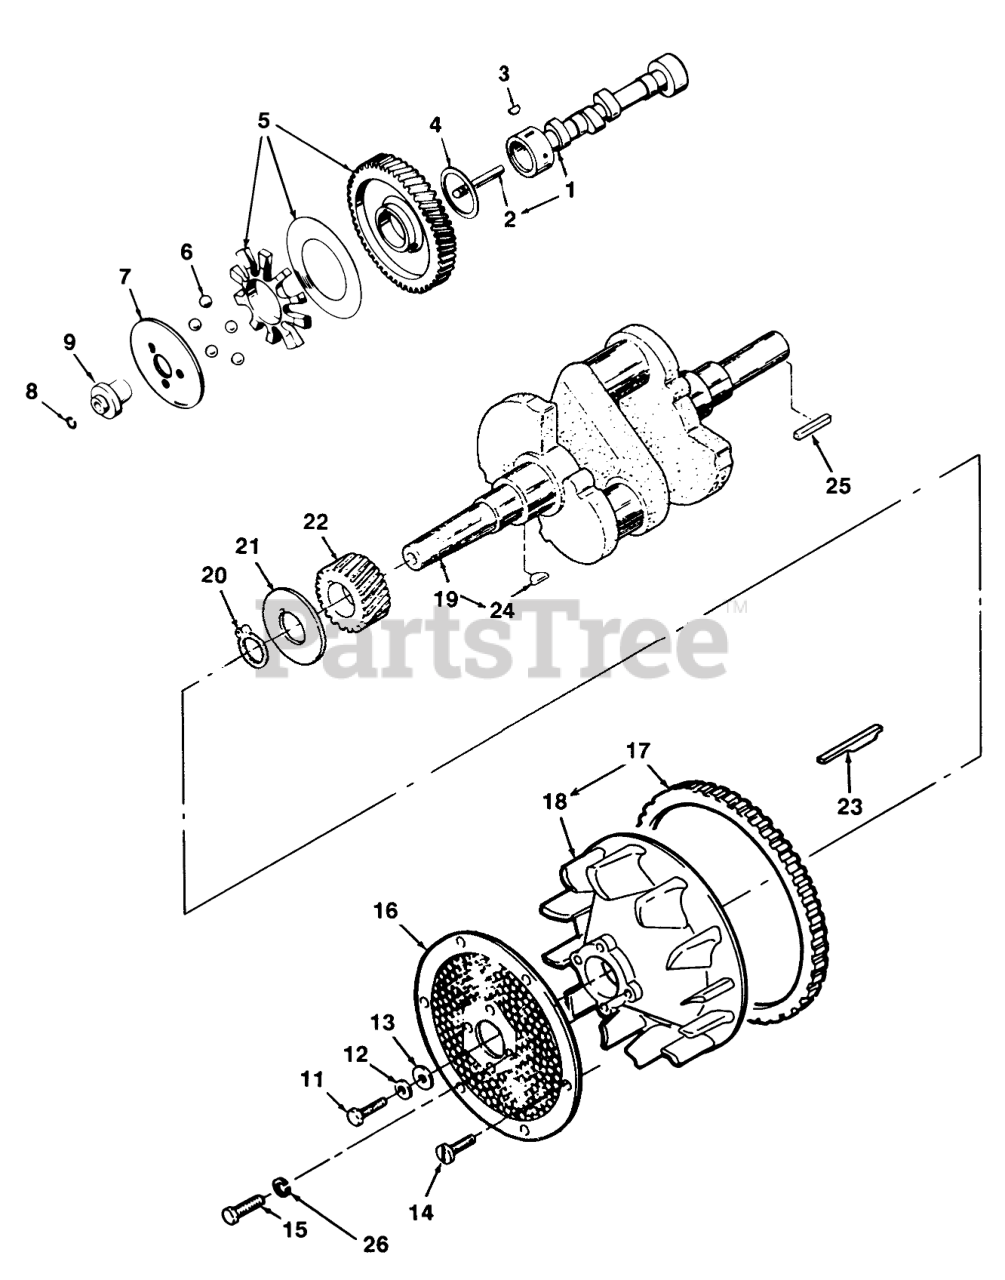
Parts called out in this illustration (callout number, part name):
1	Camshaft (Incl. Center Pin)
2	PIN-CENTER
4	WASHER-THRUST
5	Gear-Camshaft (Incl. Plate & Spacer)
6	BEARING
7	CUP-GOVERNOR
9	HUB-GOVERNOR CUP
11	Bolt-Special
12	WASHER-FLAT
13	WASHER-FLAT
14	Bolt
15	HX HD LOCK CAPSCREW
16	AIR INLET SCREEN
17	Ring Gear
18	Flywheel (Incl. Ring-Gear)
19	Crankshaft (Incl. Keys)
21	WASHER
23	KEY-FLYWHEEL
25	Key
26	WASHER - LOCK (5/16")
